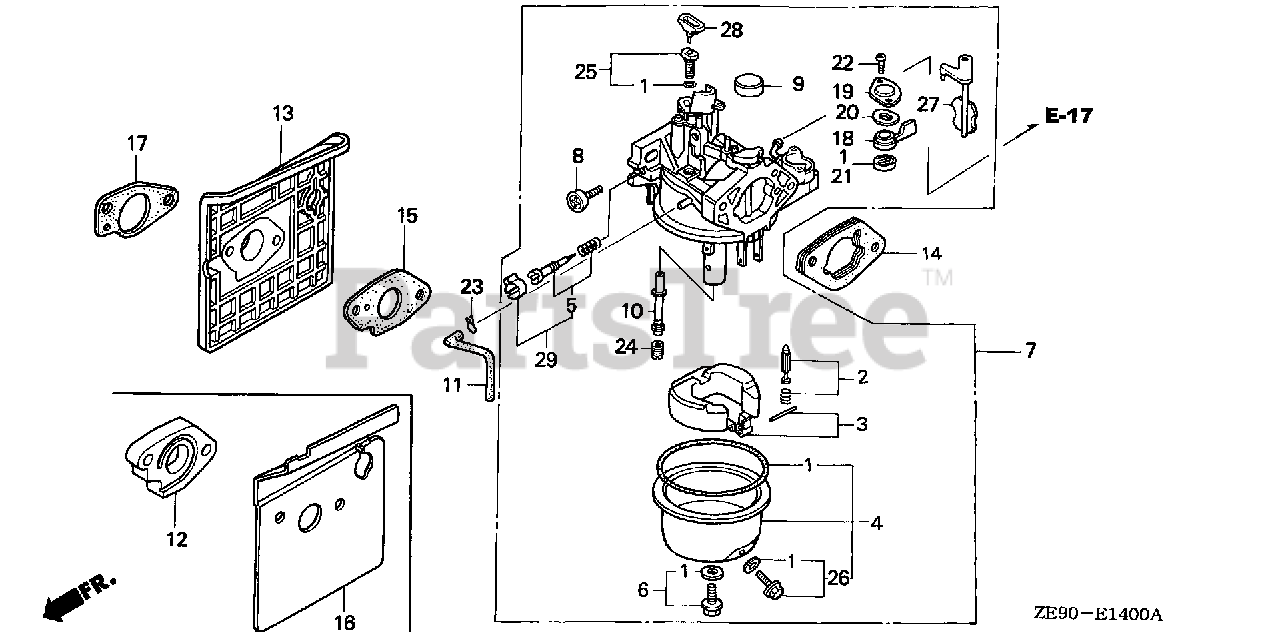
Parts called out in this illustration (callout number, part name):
1	GASKET SET (CARBURETOR NO.) (EXCEPT 16173-001-004)
2	VALVE SET, FLOAT
4	CHAMBER SET, FLOAT
6	SCREW SET
7	CARBURETOR ASSY. (BE81A C)
8	SCREW, THROTTLE STOP
9	CAP, CHOKE DUST
10	NOZZLE, MAIN
11	TUBE, AIR VENT (75MM)
13	INSULATOR, CARBURETOR
14	SPACER, CARBURETOR
15	GASKET, CARBURETOR
17	GASKET, INSULATOR
18	LEVER, PETCOCK
19	PLATE, LEVER SETTING
20	SPRING, PETCOCK LEVER
21	GASKET, PETCOCK (CARBURETOR NO.)
22	SCREW, PAN (3X6)
24	JET, MAIN (#85)
24	JET, MAIN (#88)
24	JET, MAIN (#90)
24	JET, MAIN (#82)
25	JET SET, PILOT (#38)
26	SCREW SET, DRAIN
28	COLLAR, SETTING
29	SCREW SET, PILOT
